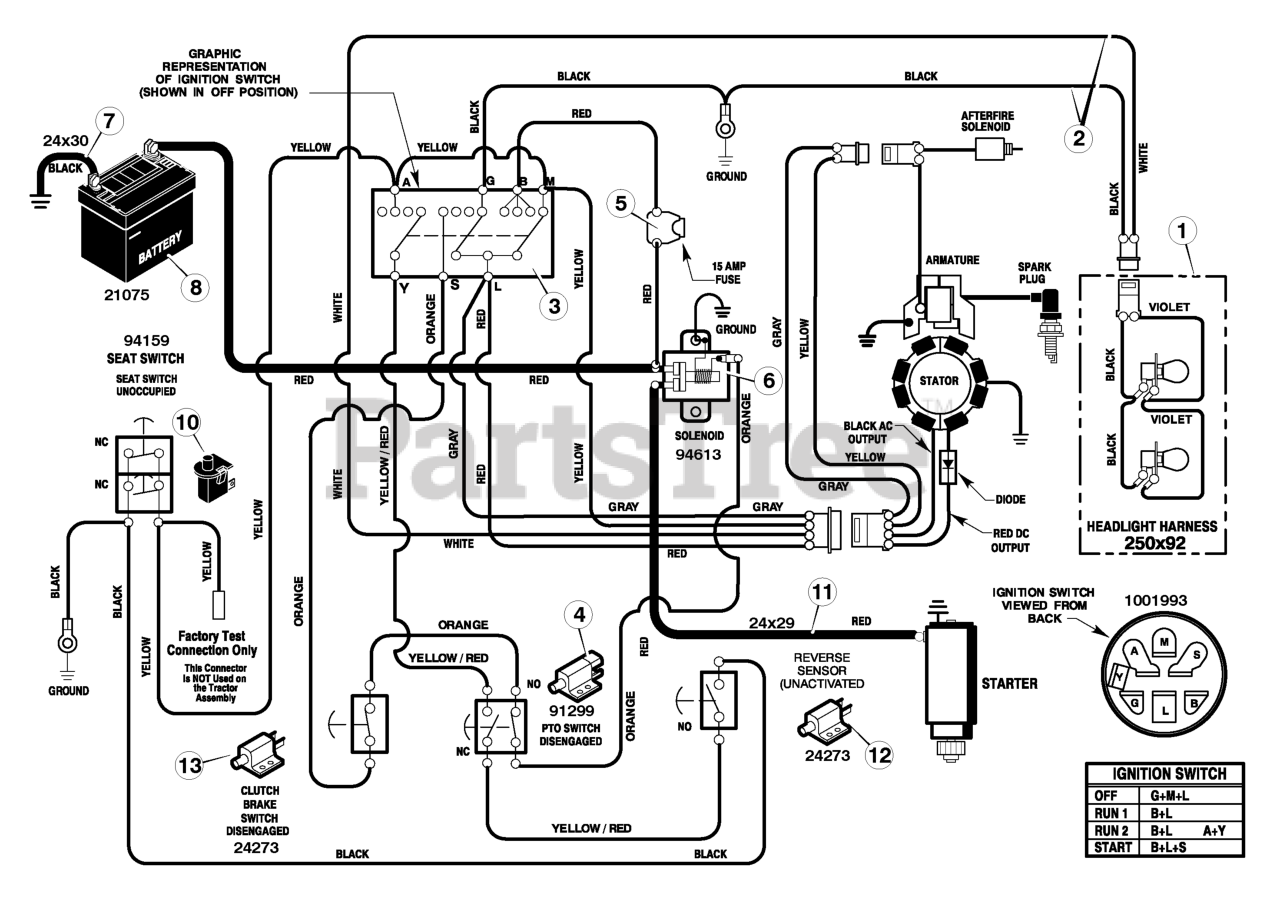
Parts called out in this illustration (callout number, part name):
1	Harness, Light Wire
2	Harness, Chassis Wire
3	Switch, Ignition
4	Switch, Limit (PTO)
6	Solenoid
7	Cable, Battery Ground
8	Battery
10	Switch, Seat Sensor
12	Switch, Select Reverse3
13	Switch, Select Reverse3
